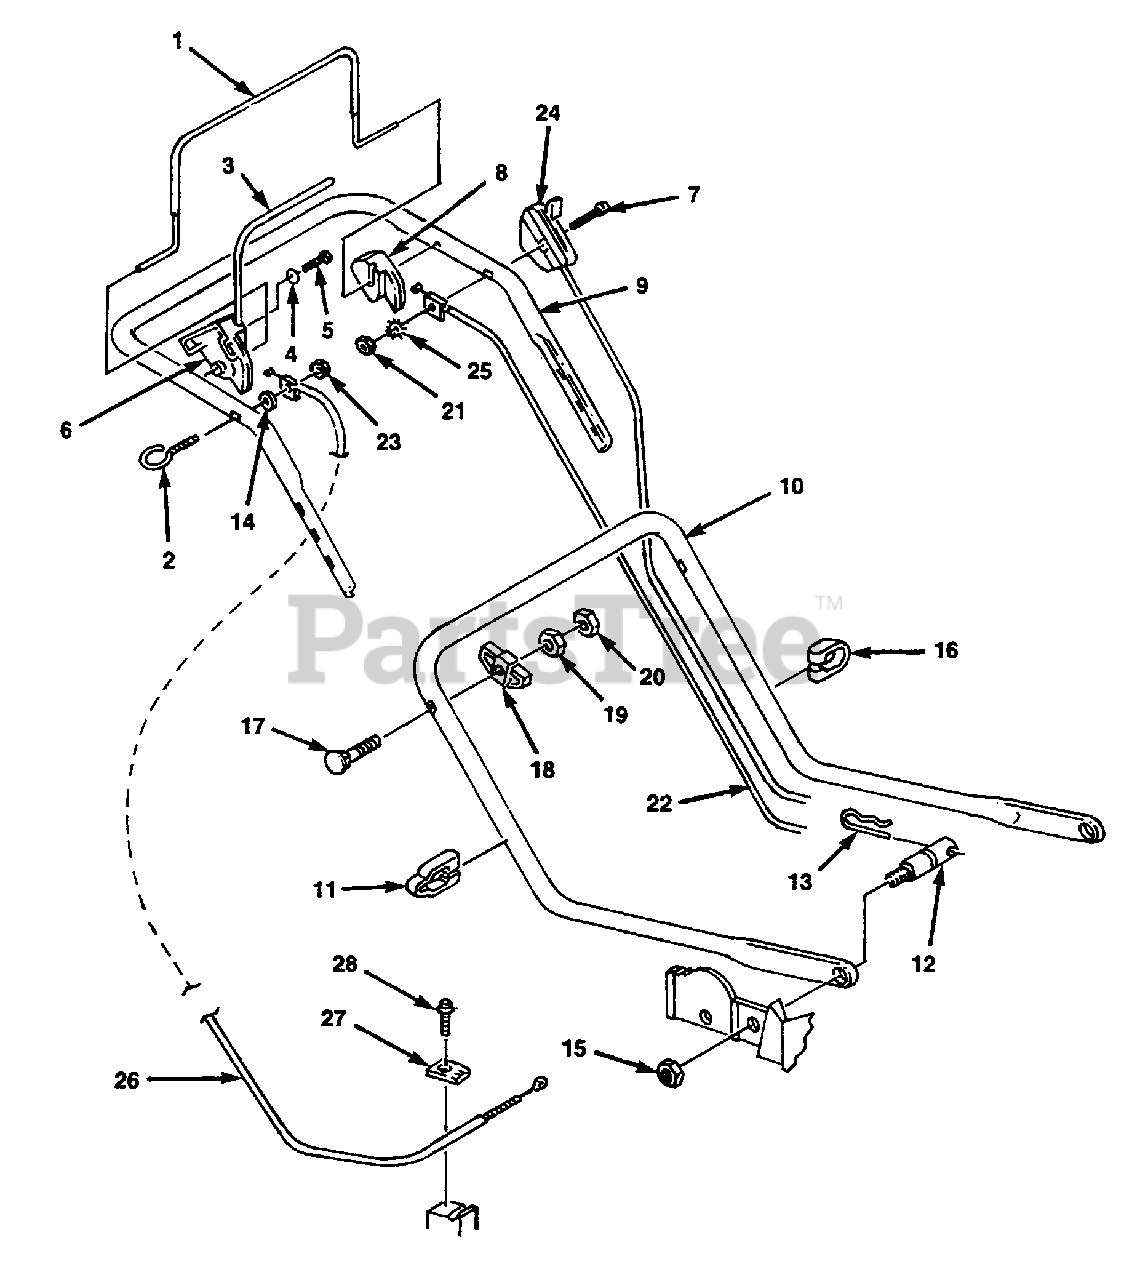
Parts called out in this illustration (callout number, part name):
1	BAIL- Brake
3	TRACTION BAIL
4	WASHER
5	SCREW
6	ACTUATOR- R.H.
7	BOLT- Sq. neck
8	ACTUATOR- L.H.
9	HANDLE- Upper
10	HANDLE- Lower
11	CLAMP- Cable (single)
12	STUD- Handle mtg.
13	PIN- Cotter hair
15	NUT- Hex flange 5/16-18
16	CLAMP- Cable (double)
17	BOLT- Sq. neck
18	KNOB- Handle
19	NUT- Hex locking 5/16-18
20	NUT- Hex locking 5/16-18
21	NUT- Hex
22	CONTROL- Manual start
23	NUT- Hex locking 1/4-20
24	CONTROL- Throttle
26	CABLE- Traction
27	CLAMP
28	SCREW- Hex hd. (1/4-20 x 5/8")
